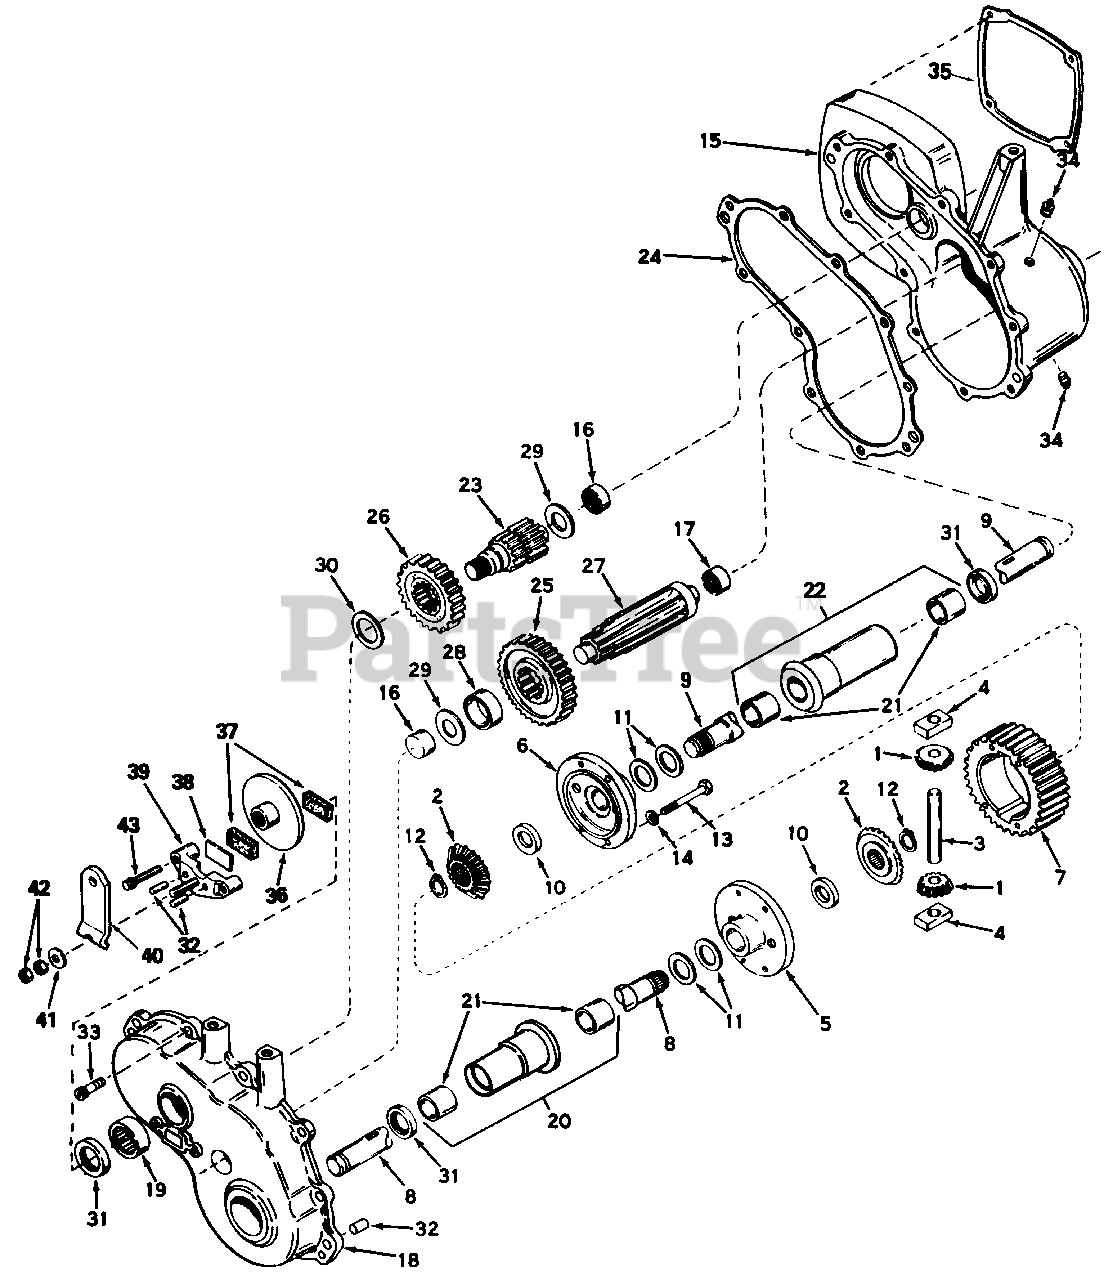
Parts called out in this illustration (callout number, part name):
1	PINION, Bevel
2	GEAR, Bevel
3	PIN, Drive
4	BLOCK, Drive
5	CARRIER, Differential
6	CARRIER, Differential
7	GEAR, Ring
8	AXLE (13-7/32" long)
9	AXLE (15-3/16" long)
11	WASHER, Thrust
12	RING, Snap
13	SCREW, Hex Hd., 1/4-20 x 2-1/4
14	LOCKWASHER, 1/4
15	CASE ASSY. (Includes Ref. Nos. 16 & 17)
16	BEARING, Needle
17	BEARING, Needle
18	COVER ASSY. (Includes Ref. Nos. 16 & 19)
19	BEARING, Needle
20	HOUSING & BUSHING ASSY. (6-5/8" long)(Includes Qty. 2 of Ref. No. 21)
22	HOUSING & BUSHING ASSY. (8-5/8" long)(Includes Qty. 2 of Ref. No. 21)
23	SHAFT, Brake
24	GASKET, Case-to-Cover
25	GEAR, Output
26	GEAR, Idler
27	SHAFT, Output
31	SEAL, Oil
32	PIN, Dowel
33	SCREW, Hex Wash. Hd., Thd. Form., 1/4-20 x
34	PLUG, Pipe
36	DISK, Brake
37	PAD, Brake
38	PLATE, Brake Pad
39	HOLDER, Brake Pad
40	LEVER, Brake
41	WASHER, Flat
42	LOCKNUT, 5/16-24
43	SCREW, Hex Wash. Hd., Thd. Form., 1/4-20 x 1
